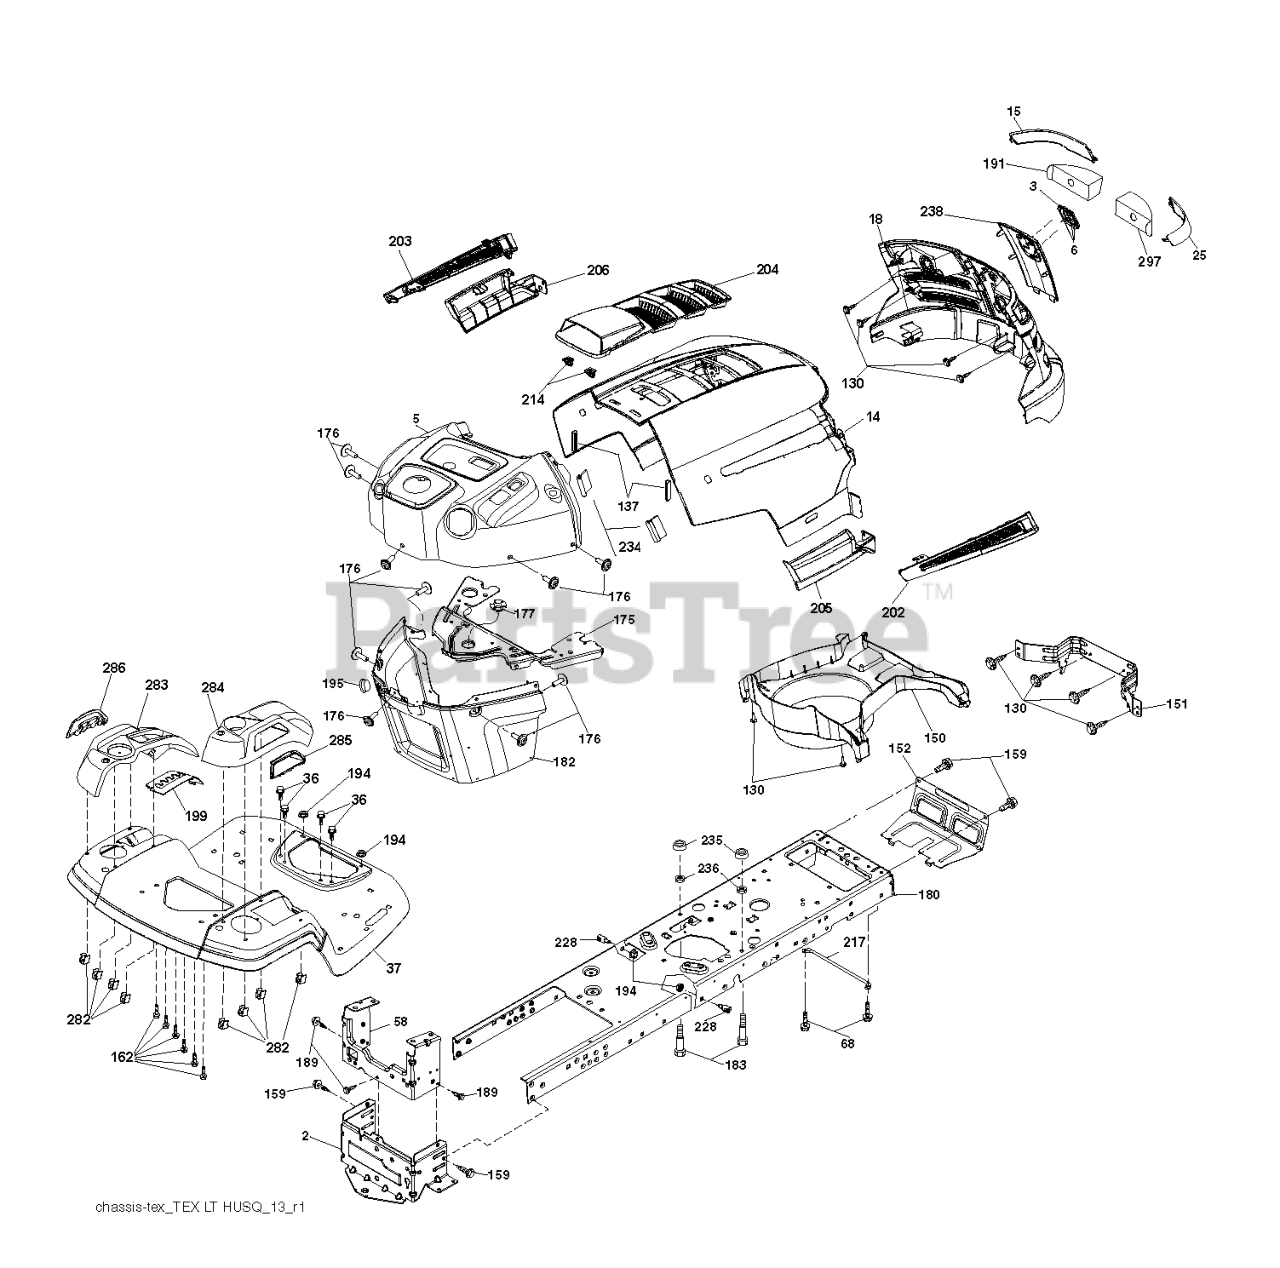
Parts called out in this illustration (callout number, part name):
2	DRAWBAR.LOWER.2PC.18/22
3	RP LOGO
5	DASH
14	HOOD
15	LENS.HUSQVARNA LT.LH
18	RP GRILLE/LENS ASM.
25	LENS.HUSQVARNA LT.RH
36	SCREW 5/16"
37	RP FENDER.TLT.FS.W/CPH.422
58	DRAWBAR UPPER 2PC SMALL FENDER
68	Screw 5/16-18 x 1/2 Hex, Self Tapping 5/16-18 x 1/2
130	SCREW.#10 X 0.750.BOS
137	BUMPER DASH
151	BRACKET PIVOT
152	SHIELD.BROWNING/DEBRIS
159	SCREW, 3/8-16X3/4
162	SCREW.HI-LO.CONSOLE
175	CROSSMEMBER
176	SCREW.#10-24X5/8.RN.QU
177	BUSHING STEERING
180	CHASSIS.STAMPING.LT/GT
182	DASH.LOWER.PREDATOR LT
183	BOLT.5/16-18X1-1/4 FULL.THREAD
189	SCREW
191	INSERT REFLECTIVE
194	NUT LOCK HEX FLANGE 5/16-18
195	PLUG DASH
199	PLATE.DECK.LIFT.HUSQ.LT
202	VENT SIDE HOOD RH
203	VENT SIDE HOOD LH
204	VENT TOP HOOD
205	SKIRT SIDE RH
206	SKIRT SIDE LH
214	CLIP.RETAINER.TINNER.
217	ROD.PIVOT.HOOD
228	STUD.FASTNER.W/ANTI-ROTATE
234	BUMPER.HOOD.TEX.HUSQVARNA
235	SPACER FENDER
236	NUT.CENTERLOCK.5/16-
238	TRIM
282	CLIP.RETAINER.CONSOLE.LT.HUSQ
283	CONSOLE.DECK.LIFT.HUSQ.N/FR.GR
285	CONSOLE INSERT RH
286	CONSOLE.INSRT.LH.HUSQ.LT.BLACK
287	SCREW 1/4X20
297	INSERT.REFLECTIVE.RH.
